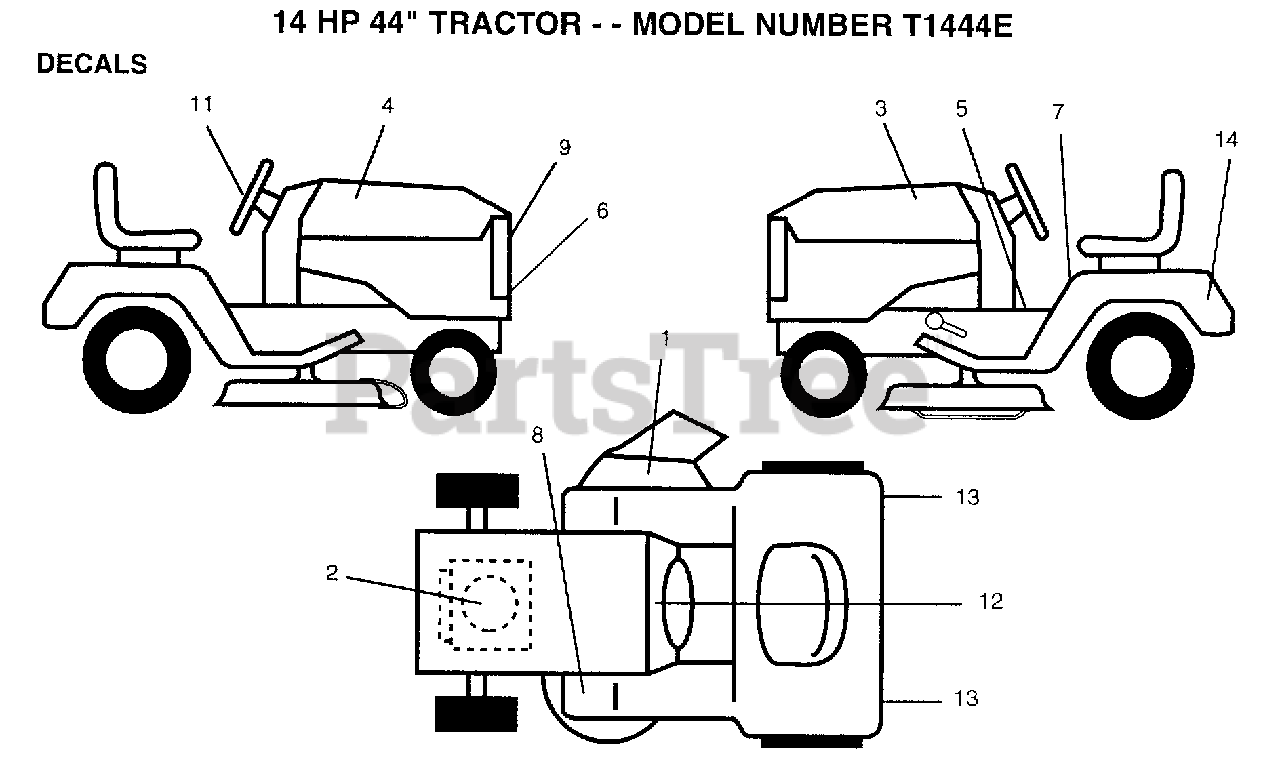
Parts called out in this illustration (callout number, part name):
1	"DECAL.V.BELT.44"""
2	DECAL.ENG.272750
3	DECAL.HD.LH.
4	DECAL.HD.RH.
5	DECAL BRAK PARK
6	"DECAL,GRILL"
7	DECAL
9	DECAL.GRIL.T1444E
11	DECAL.STRG.WHEEL
12	DECAL.DASH.INST.
13	REFLECTOR-TAIL YT
14	"DECAL,FENDER T"
